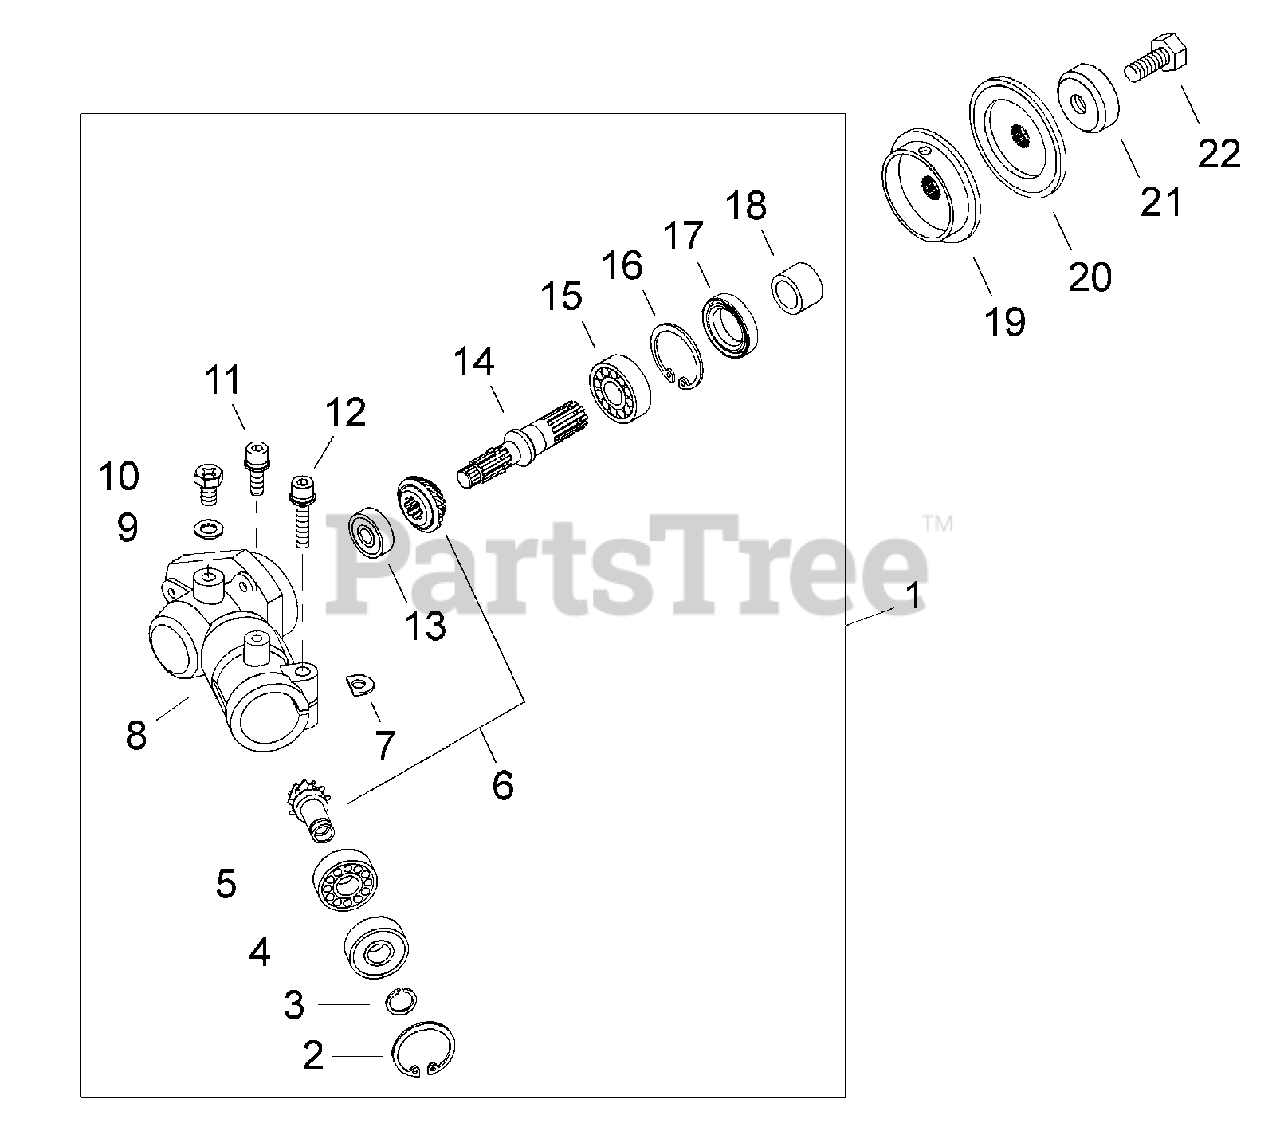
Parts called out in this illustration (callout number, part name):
1	GEAR CASE ASSY
2	RING, SNAP Ø24
3	RING, SNAP
4	BEARING, BALL 609ZZ
5	BEARING, BALL 609
6	GEAR SET
7	D-WASHER
8	CASE, GEAR
9	WASHER 6.5×11.5×0.8
10	BOLT M6×10
11	BOLT M5×16
12	BOLT M5×25
13	BEARING, BALL 608 DDU
14	SHAFT, GEAR
15	BEARING, BALL 6001
16	RING, SNAP Ø28
17	SEAL, OIL
18	SPACER
19	PLATE, ADAPTOR - UPPER
20	PLATE, ADAPTOR - LOWER
21	GUARD, BOLT
22	BOLT 8
